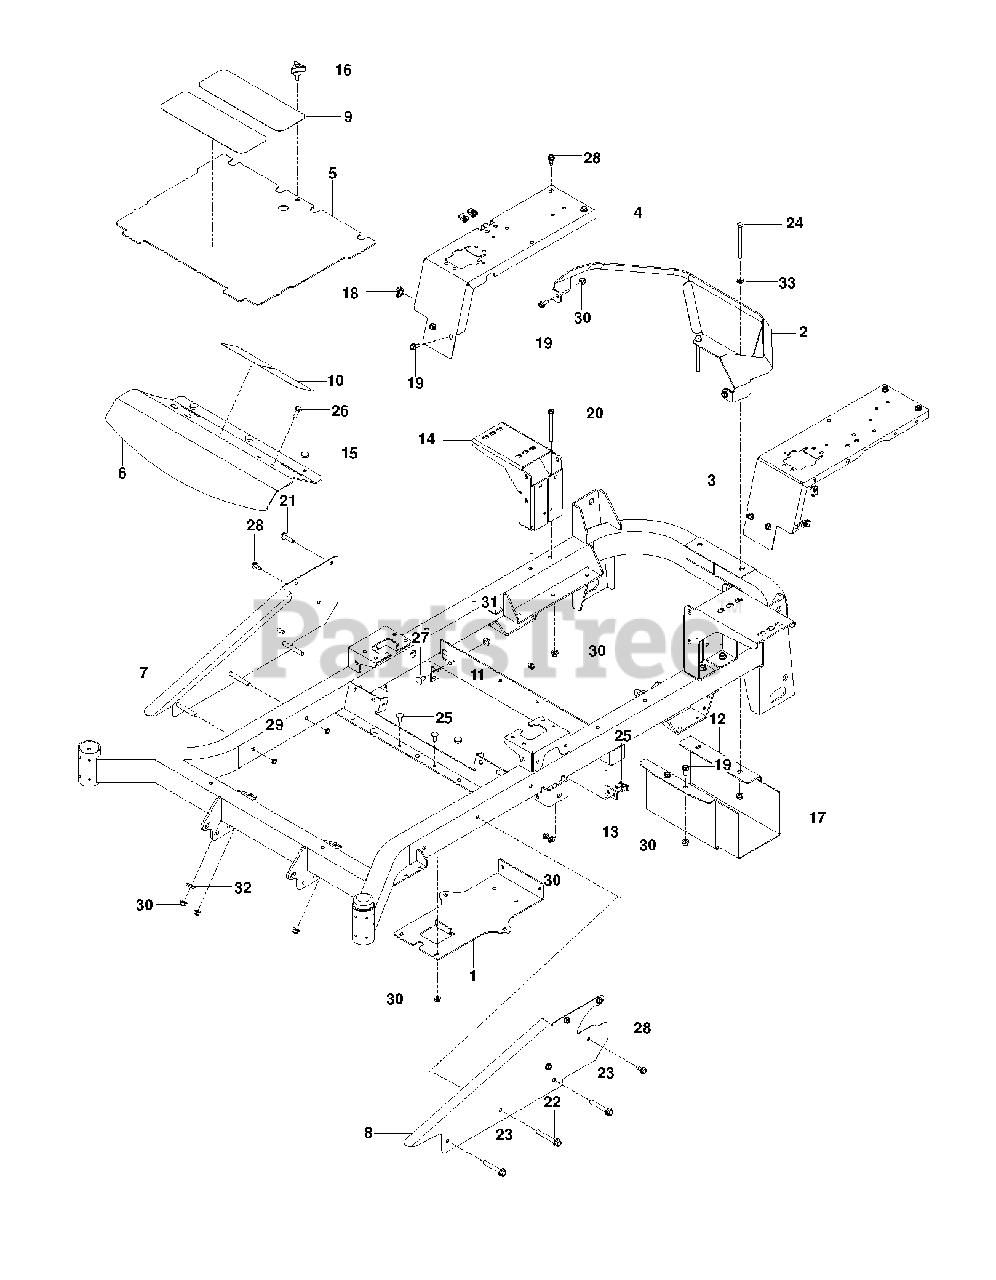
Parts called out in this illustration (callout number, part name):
1	PLATE, BATTERY, BLACK
2	GUARD, REAR MZ, GRAY
3	PANEL.FILLER.LT.ORANGE
4	PANEL.FILLER.RT.ORANGE
5	PLATE, FLOOR W/DECALS
6	PLATE, FOOTREST
7	SIDE.RT.ORANGE
8	SIDE.LT.ORANGE
9	ANTI-SKID PAD
11	BRACKET.DAMPENER.BLACK
12	SHIELD.MUFFLER.BLACK
13	STOP, DECK, EZ+
14	MOUNT, TANK, ZT BLK
15	GROMMET, BUMPER
16	KNOB W/STUD
17	HEAT SHIELD
18	U-CLIP 5/16-18 NUT RETAINER
19	HHFS 5/16-18 X 3/4
20	HHFS 5/16-18 X 3 3/4
21	HHFS 5/16-18 X 1.25 TPBLT GD 5
22	HHFS 3/8-16 X 2 3/4
23	HHFS 3/8-16 X 2.5 GR 5 ZD
24	HCS 5/16C X 4
25	BOLT 5/16C X 3/4" CARRIAGE
26	RHSNB 5/16C X 1
27	RHSNB 3/8-16 X 3/4 GR 5 BLK ZN
28	BOLT 5/16-18 X 3/4
29	NUT HEX 3/8-16 NYLON, THIN
30	5/16-18 NYLOC FLANGE NUT
31	NUT 3/8-16 HEX FLG NYLOC ZD
32	WASHER 1/2" FLAT
33	FLAT WASHER 5/16 SAE
